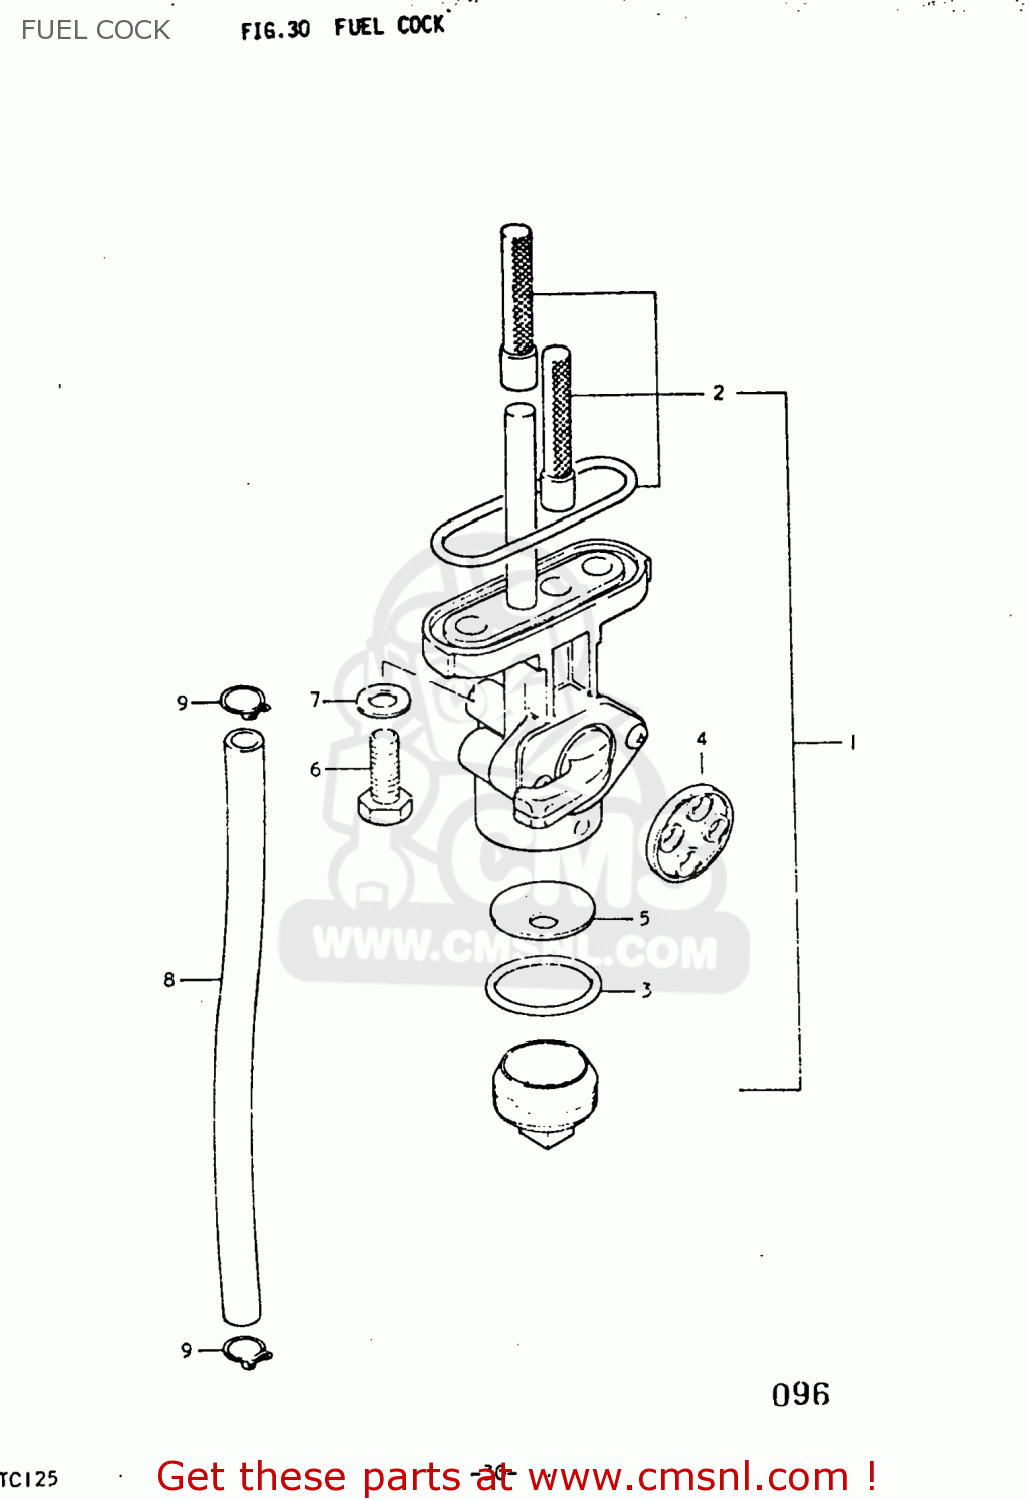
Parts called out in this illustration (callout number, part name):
1	COCK ASSEMBLY,FUEL
2	FILTER SET,FUEL COCK
3	GASKET,FILTER (NAS)
4	GASKET,LEVER (NAS)
5	NET,STRAINER
6	SCREW
7	GASKET
8	HOSE
9	CLIP
